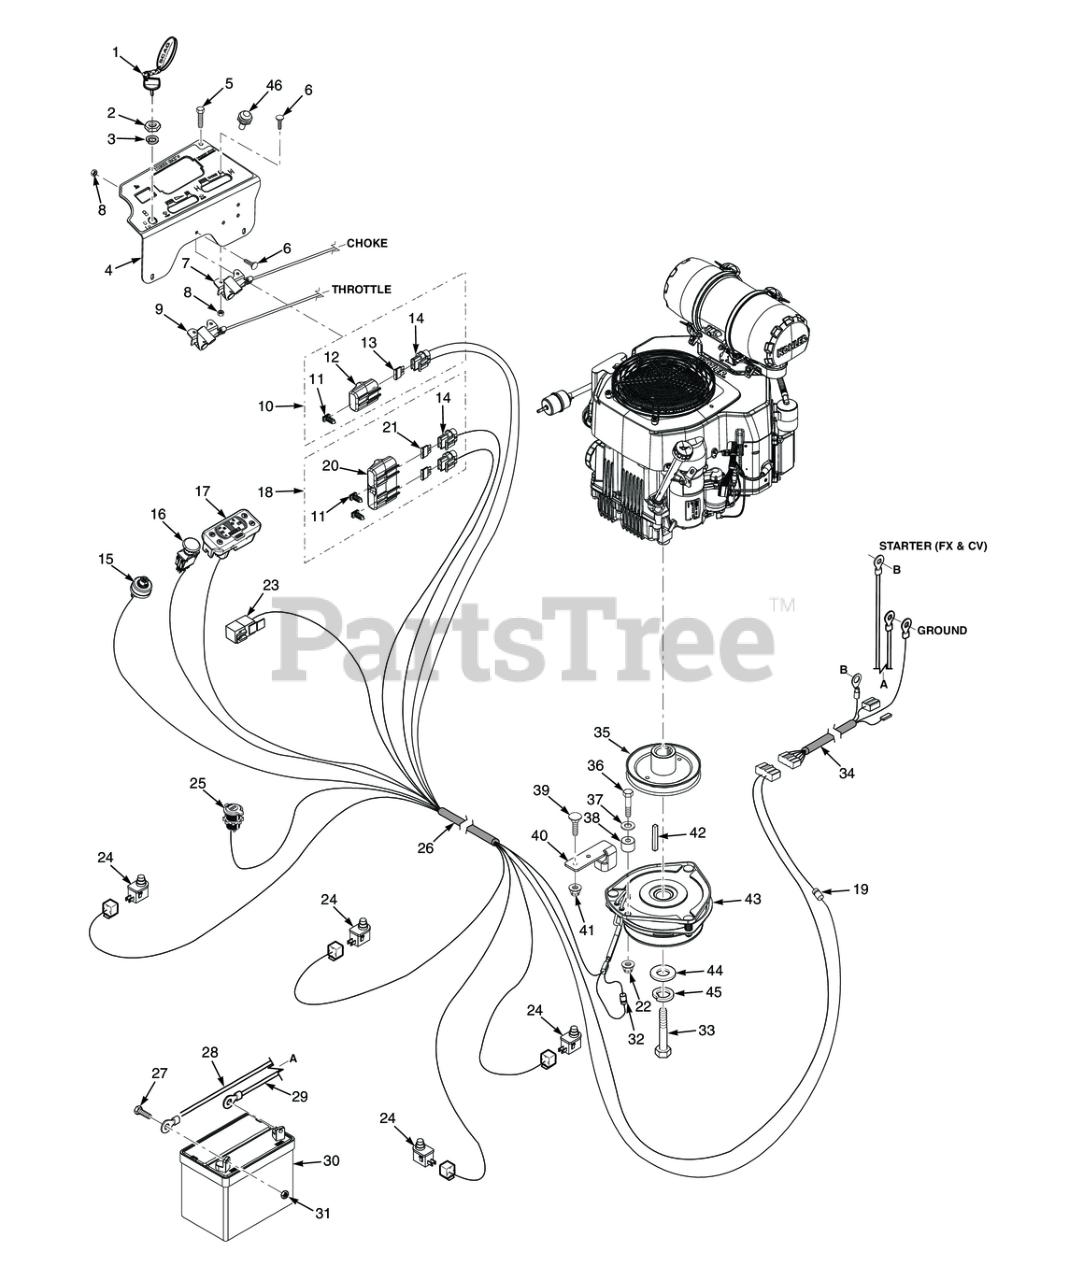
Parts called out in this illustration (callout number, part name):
1	Key, Assembly w/Fob
2	Nut, 5/8-32 Special
3	LOCK WASHER, 5/8" INTERNAL TOOTH
4	Instrument Panel w/Decal
5	CAP SCREW, 1/4-20 X 1/2" SERRATED FLANGE HEX
6	Bolt, Carriage #10-24 x 1/2"
7	Throttle Control Cable (Kawasaki FS / FX, Kohler CV)
8	Nut, Elastic Stop #10-24
9	Throttle Control Cable (Kawasaki FS / FX, Kohler CV)
10	Single Fuse Assy., Excluding Fuse
11	Clip, Fuse Holder
12	Cover, Sealed Single
13	Fuse, 5 Amp
14	Fuse Holder Assembly
15	KEY SWITCH(INCLUDES MOUNTING HARDWARE)
16	Switch, PTO - 10 Amp
17	Tiger Eye, Cluster Gauge
18	Double Fuse Assy.
19	Decal, Forward Speed Selector
20	Cover, Sealed Double
21	FUSE, 20 AMP BLADE TYPE AUTOMOTIVE
22	HEX NUT, ELASTIC STOP LOCK, 5/16-18
23	Relay, 12V 40 AMP Standard
24	Switch, Interlock, Normally Open
25	Power Plug, 12V
26	Wire Harness
27	Bolt, Hex Head 1/4-20 x .5" Battery, (Not Available Through Scag)
28	Battery Cable, 25" Red
29	Battery Cable, 27" Black (35BV & 37BV-EFI) - Briggs & Stratton
30	Battery, 350 CCA
31	Nut, 1/4 - 20 Hex
32	Diode, 600V 6 Amp
33	Bolt, Hex Head 7/16-20 x 2-3/4" w/ Patch
34	Wire Harness Adapter Yamaha MX
35	Pulley, 5.75" Dia. - 1.125 Bore
36	Bolt, Hex Head 5/16-18 x 2-1/2" (x3) (35BV & 37BV-EFI)
37	Flatwasher, 5/16-.375 x .875 x .083 (35BV & 37BV-EFI)
38	BUSHING, UHMW
39	Bolt, 5/16-18 x .75 RHSN Carriage
40	ANTI ROTATION
41	Nut, Flange Head Elastic Stop 5/16-18
42	Key, 1/4 x 1/4 x 3-1/2"
43	Clutch w/Tag GT3.5--FE05 (61)
44	Flatwasher, 7/16-.469 x 1.75 x .25 (48, 52)
45	Lockwasher, 7/16� Spring
46	Indicator Light, Glow Plugs (Includes Mounting Hardware)
